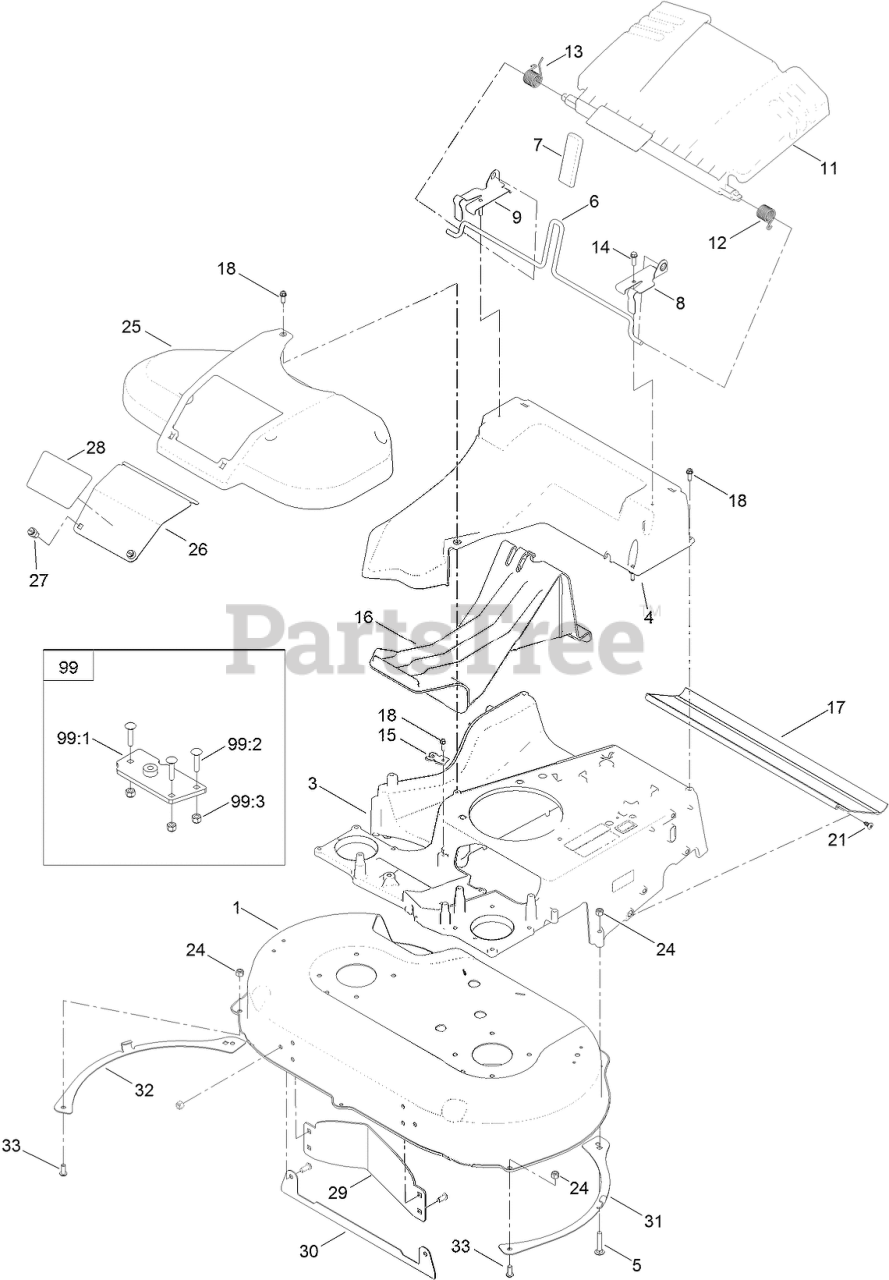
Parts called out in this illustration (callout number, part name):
1	HOUSING ASM
4	CHUTE
5	SCREW-CARR
6	ROD-RELEASE, HANDLE
7	GRIP-LEVER
8	BRACKET-DOOR, LH
9	BRACKET-DOOR, RH
11	REAR DEFLECTOR ASM
12	SPRING-TORSION
13	SPRING-TORSION
14	SCREW-HWH
15	BRACKET-CABLE, TRACTION
16	PLUG-MULCH
17	SHIELD-TRAILING
18	SCREW-HWHTF
21	SCREW-PTH
24	NUT-LOCK, NI
25	COVER-BELT
26	DOOR-ACCESS
27	FASTENER
28	DECAL-ACCESS PANEL
29	BAFFLE-CONTROL
30	PLATE-DECK
33	SCREW-HSBH
99	FRAME PLATE KIT
99:1	PLATE-FRAME
99:2	SCREW-CARR
99:3	NUT-LOCK, NI
